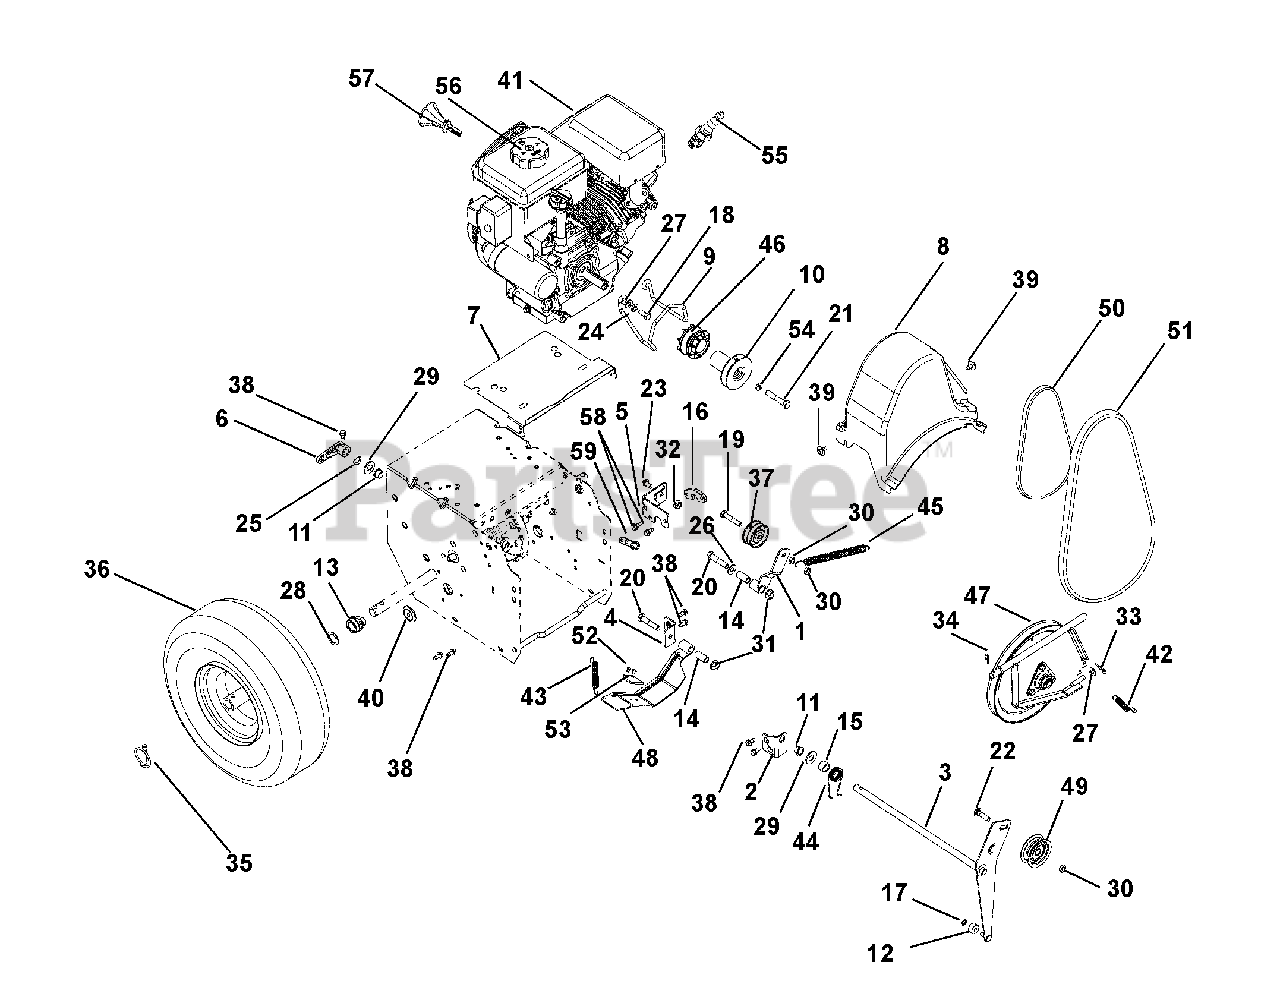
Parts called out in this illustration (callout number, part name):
1	ARM, TRACTION IDLER
2	BRACKET, MOUNT - IDLER ARM
3	WELDMENT, ATTACHMENT IDLER ARM
4	BRACKET, MOUNT - BRAKE
5	WELDMENT, FRAME BRACKET
6	ARM, CLUTCH - ATTACHMENT
7	BAFFLE,ENGINE,SMALL BLOCK
8	COVER, COMPACT BELT
9	FINGER, BELT
9	BELT FINGER
10	SHEAVE,AUGER 3/4" PM
10	SHEAVE, AUGER DRIVE
11	BUSHING, POLYLINER-.50 SPLIT
12	BSHG,SLV .265 X .625 X .375
13	BSHG .75X1.125X.65
14	BSHG-SLV .385X.500X1.045
15	BSHG-SLV .510X.751X.475
16	SPACER, SWING GATE
17	RG-RTNG-EXT .250X.010
18	BLT-HEX .31-24X.75 YWZC GR5
19	@BLT-HEX .31-18X1.75 GR5 YWZC
20	@BLT-HEX .38-16X1.75 GR5 YWZC
21	BLT-HEX .38-24X2.0 YWZC
22	BLT-RDHDSQSHNK.31-18X1.13 G5YZ
23	@BLT-RHDSSQNK .31-18X.62 G5YZ
24	WSHR-LK .312X.097 HVY YWZC
25	WSHR-WAVE .50X.75X.015 .13FRHT
26	@WSHR-FL-STL.406X.812X.065 YWZ
27	@WSHR-FL-STL.344X.688X.065YWZC
28	WSHR-FL-STL.754X1.125X.062YWZC
28	BSHG-SLV .75X1.12X1.062 NYL BK
29	@WSHR-FL-STL.531X1.06X.095YWZC
30	@NUT-LK-CTR-JAM .31-18 YWZC
31	@NUT-LK-TOP-FLG .38-16 YWZC
32	@NUT-LK-TOP-FLG .31-18 YWZC
33	PIN-HAIR INT .08X.18X1.18 YWZC
34	CLIP, SPRING
35	PIN-LOK .31X1.75
36	TIRE/WHEEL, 15X5.00-6 K398A
36	TIRE, 15" K398A
36	TIRE/WHEEL, 13X4.10-6 K398A
36	TIRE, 13" K398A
37	KIT, FLAT IDLER
38	SCR-TAP .25-20X.50 HWH TR YWZ
39	SCR-TAP .25-20X.5 CAPTIVE
40	PLUG, HOLE - 1.00" FLEXTEMP
41	ENGINE, SNO-TEK 208 120V
41	ENGINE,LCT STORMFORCE 208 240V
41	ENGINE, SNO-TEK 136 240V
41	ENGINE, SNO-TEK 136 RECL
42	SPRING, EXT. .043X.438X1.64
43	SPRING-EXT .437 X .438 X 2.64
44	SG-TORS .075 X .955
45	SPRING, EXTENSION
46	SHEAVE, TRACTION
47	PLATE, SWING - ASSEMBLY
48	BRAKE ARM W/PAD
49	KIT, FLAT IDLER
50	V-BELT, 3L-WRAPPED
51	V-BELT, HA-RAW EDGE
52	RVT-POP .187 YZ
53	PAD, BRAKE
54	@WSHR-LK .38X.094 REG YWZC
55	PLUG, SPARK
56	CAP, FUEL TANK BLACK
57	KEY, PUSH/PULL LCT (2/PACKAGE)
58	SCR-TAP-PM .25-20X.75 TR YWZ
59	SUPPORT BUSHING, SWING GATE
